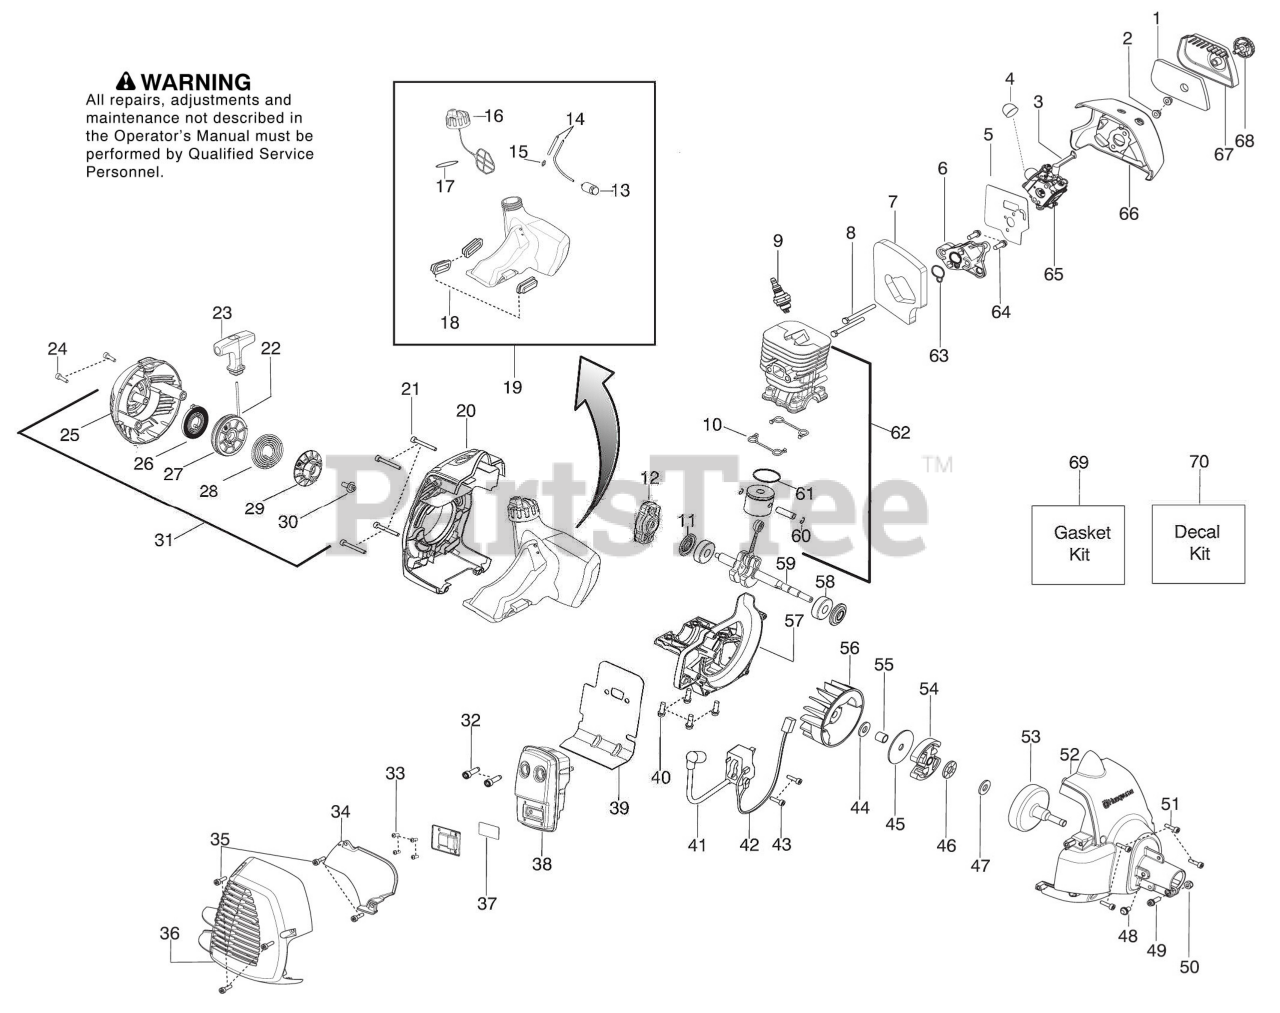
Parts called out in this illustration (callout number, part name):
2	Nut - Carb. Screw
3	Lever - Choke
4	Bulb - Purge
5	Kit - Carb. Gasket
6	Adaptor - Carb.
7	Foam - Gasket
9	Plug - Spark (RCJ-8Y)
10	Seal - Cylinder
11	Seal - Crankshaft
12	Assy - Starter Pawl
13	Assy - Fuel Filter
14	Kit - Fuel Line
15	Fitting - Fuel line
16	Assy - Cap w/ret.
17	O-ring - Fuel Cap
18	Isolator - Fuel Tank
19	Kit - Fuel Tank Assy.
20	Shroud - Rear
22	Kit - Rope
23	Handle - Starter
25	Hsg. - Starter w/eyelet
26	Kit - Spring
27	Kit - Starter Pulley
28	Spring - Driver
29	Pulley - Driver
31	Assy - Starter Hsg
32	Bolt - Muffler
33	Screw
34	Shield - Heat
36	Guard - Muffler
37	Kit - Spark
38	Kit - Muffler
39	Gasket - Paper Met.
42	Assy - Leadwire
45	Washer - Clutch
46	Bearing - Thrust
47	Washer - Thrust
52	Assy - Fan Housing
53	Assy - Clutch Drum
54	Assy - Clutch
57	Crankcase - Cast
59	Assy - Crankshaft
60	Retainer - Piston Pin
61	Ring - Piston
62	Kit - Piston/Cyl.
63	Seal - adaptor
65	Kit - Carb.
66	Airbox
67	Cover - Air Box
68	Assy - Knob
69	Kit - Gasket
70	Kit - Decal
